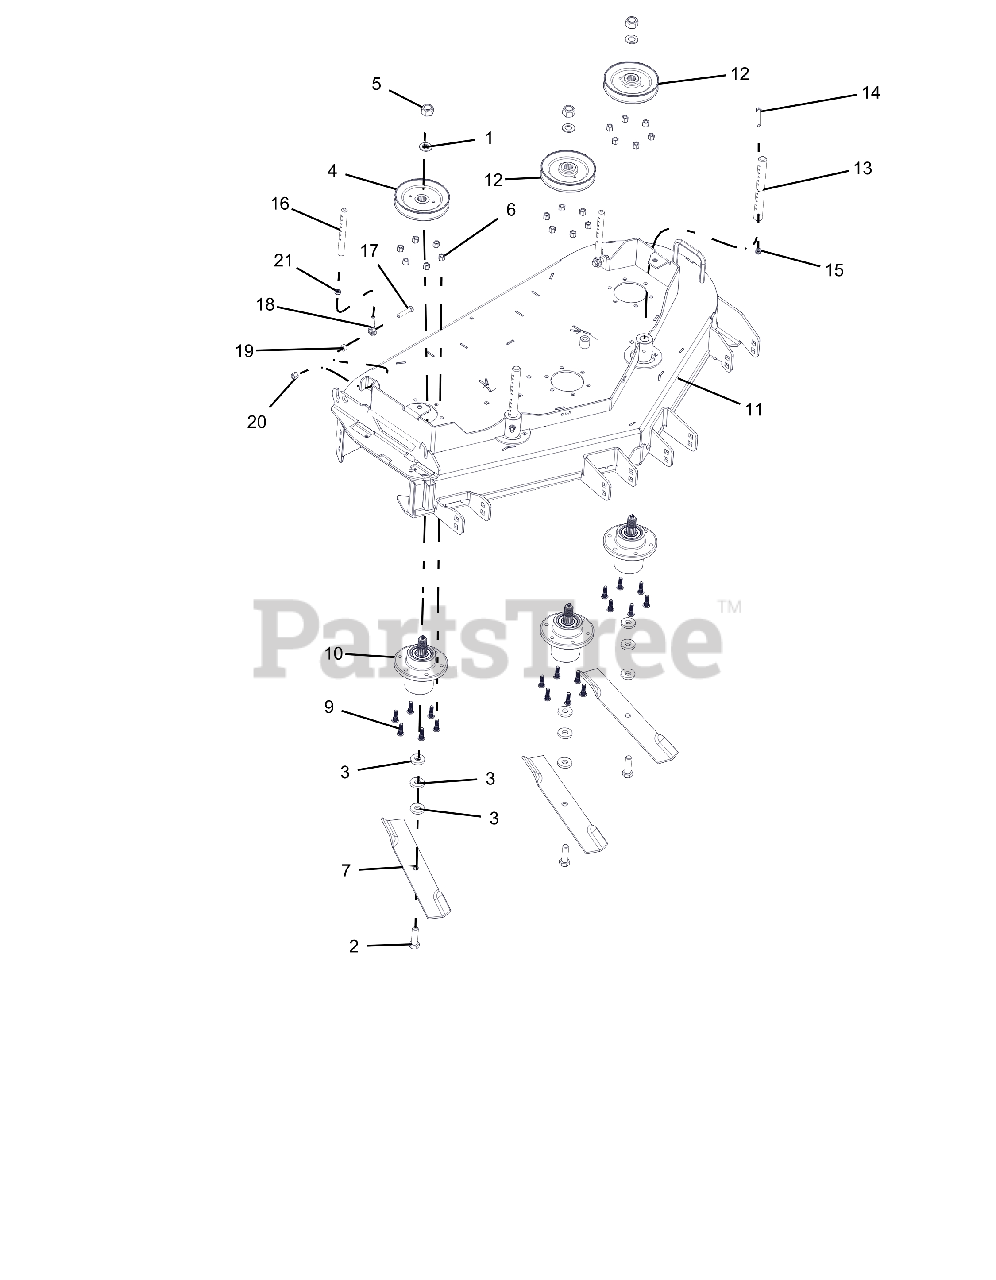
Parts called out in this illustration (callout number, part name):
1	WASHER, .75X1.3125X.120
2	BLT-HEX .62-11X2.00 GR8 YWZC
3	WSHR-FL-STL .630X1.50X.25 YWZC
4	PULLEY, SPINDLE 5.75 X .76-BLACK
5	LOCKNUT, 3/4-16 CROWN GR5 Y
6	NUT-LK-NYL .38-16 YWZC
7	BLADE, 16.50 LO-LIFT
8	PULLEY, V-5.75 OD X 1.51 ID
9	BOLT, 3/8-16 X 1.25 RDHD RIBNK/O
10	ASSY, SPINDLE HOUSING
11	ASSY, 48 FLWLKDECK W/DECALS
12	PULLEY, SPINDLE 5.75 X .25-BLACK
13	PIN, FRONT HOC
14	BLT-HEX .31-18X2.50 GR8 YWZC
15	@NUT-SPNLK-FLG .312-18 YWZC
16	ROD, REAR HOC
17	BLT-HEX .38-16X1.75 GR5 YWZC
18	ROD, END 3/8 RH REV
19	BSHG, SLV REV
20	NUT-LK-NYL .38-16 YWZC
21	NUT-JAM .375-24 YWZC
